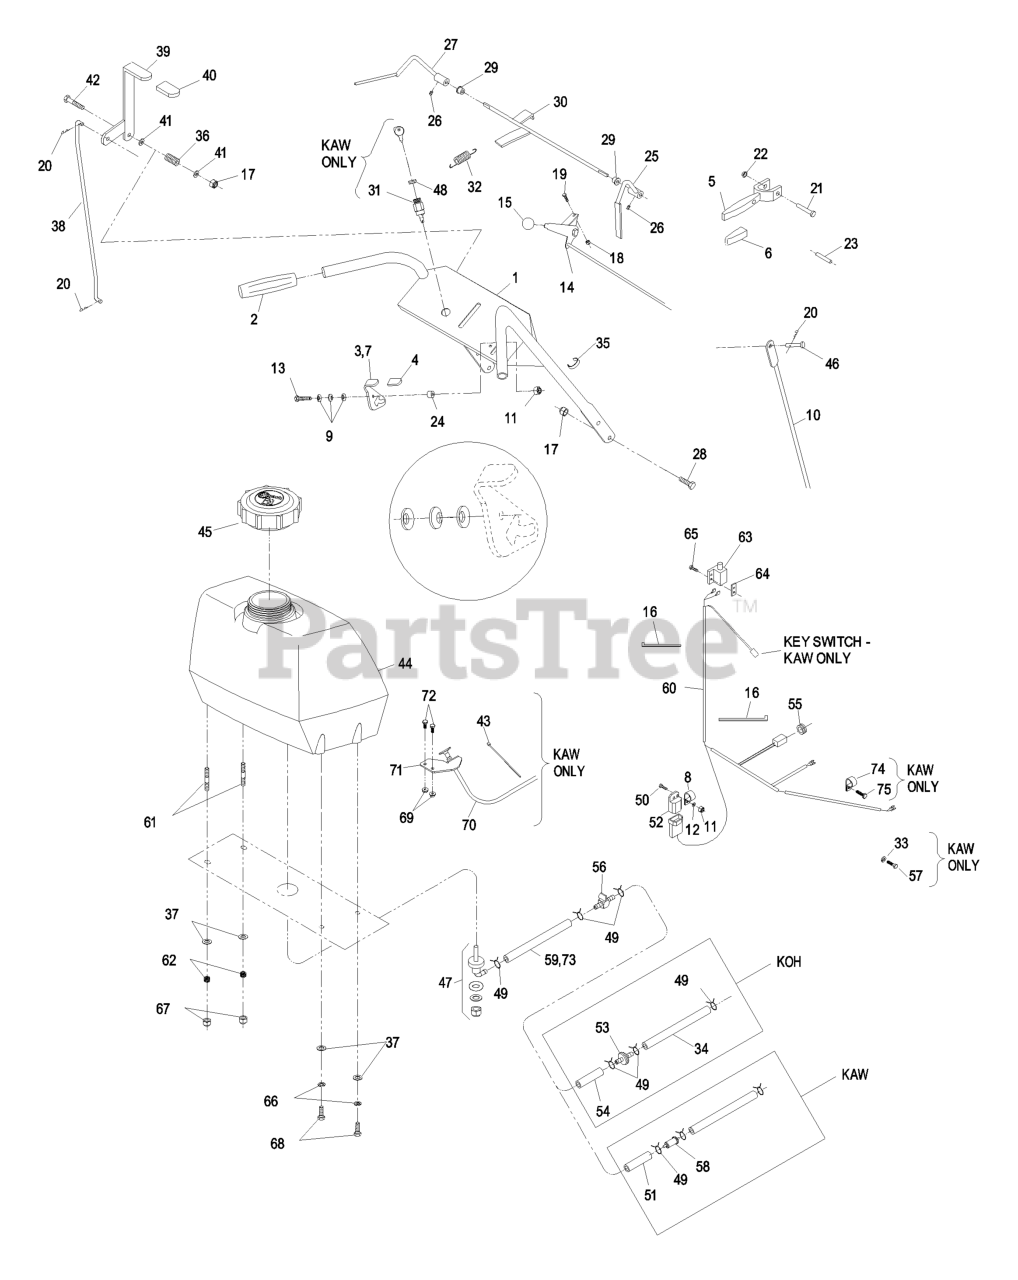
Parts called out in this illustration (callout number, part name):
1	KIT,HANDLE/DECALS METRO
4	GRIP-LATCH
5	DRIVE LEVER ASM
6	GRIP-LEVER, DRIVE
8	CLIP-LOOM
9	WASHER-SPRING
10	LINKAGE-WHEEL, DRIVE
11	NUT-LOCK, NI
12	WASHER-FLAT
13	SCREW-HH
14	CABLE-CONTROL, THROTTLE
15	KNOB-BALL
16	TIE-CABLE
17	NUT-LOCK, NI
18	NUT-LOCK, NI
19	BOLT-CARR
20	PIN-COTTER
21	PIN-LEVER, DRIVE
22	NUT-PUSH
23	PIN-ROLL
25	LEVER-RH
26	SCREW-SET
27	LEVER-LH
28	SCREW-HH
29	BUSHING-NYLON
30	WLD,ROD OPC
31	SWITCH & KEY (INCLUDES NU
32	SPRING-EXTENSION
33	WASHER-LOCK
34	HOSE-LINE, FUEL
35	CLIP-CABLE
36	SPRING-COMPRESSION
37	WASHER-PLAIN
38	LINKAGE-BLADE, UPPER
40	GRIP-LEVER
41	WASHER-FLAT
42	SCREW-HH
43	TIE-PLASTIC
44	ASM,FUEL TANK W/B
46	PIN-CLEVIS
47	FITTING-FUEL, BULKHEAD
48	NUT-SWITCH, IGNITION
50	SCREW-HH
51	HOSE-FUEL
52	MODULE-INTERLOCK
54	HOSE-LINE, FUEL
55	GROMMET
56	VALVE-FUEL
57	SCREW-HH
58	Kawasaki Pn 41019-1055 W/6" Fuel Line (Kaw)
59	HOSE-FUEL
60	HARNESS-WIRE
61	STUD
62	SPRING-TANK, FUEL
63	SWITCH-OPEN, NORMALLY
64	PLATE-TAPPED
65	SCREW-PPH
66	WASHER-LOCK
67	NUT-LOCK, NI
68	SCREW-HH
70	CABLE-CHOKE
71	BRACKET-CABLE, CHOKE
72	SCREW-HH
73	HOSE-FUEL
74	CLIP-LOOM
75	SCREW-HH
